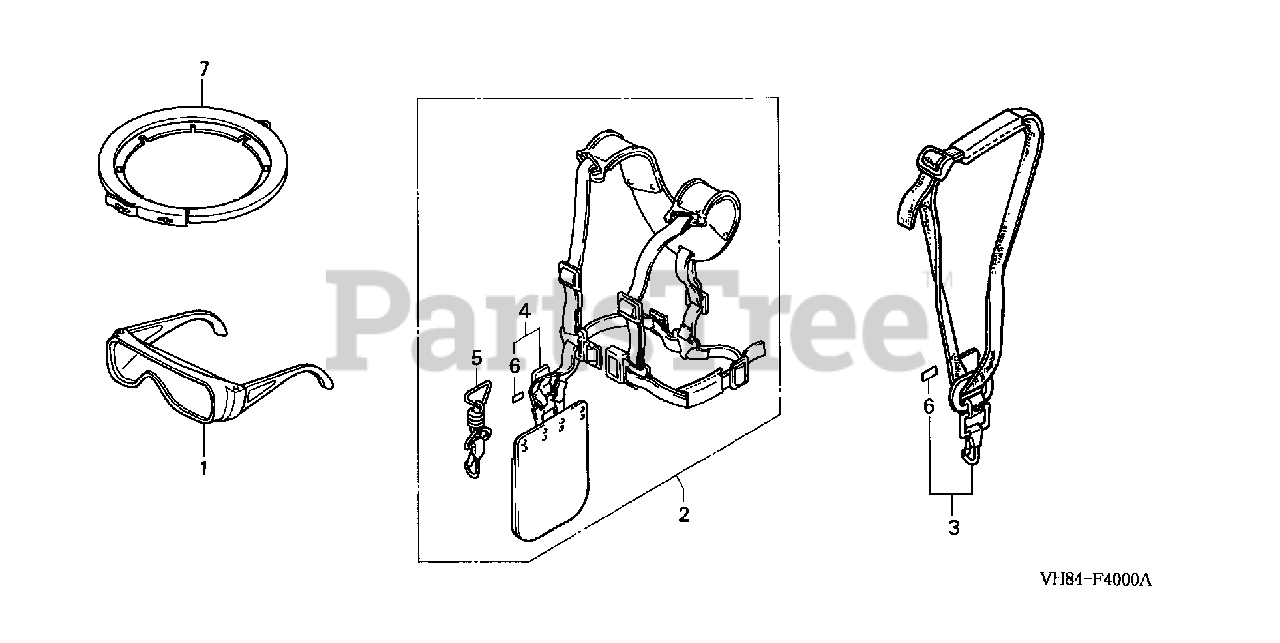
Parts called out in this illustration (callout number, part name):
1	PROTECTOR, EYE
3	BELT ASSY., SHOULDER
6	MARK, QUICK RELEASE (E)
